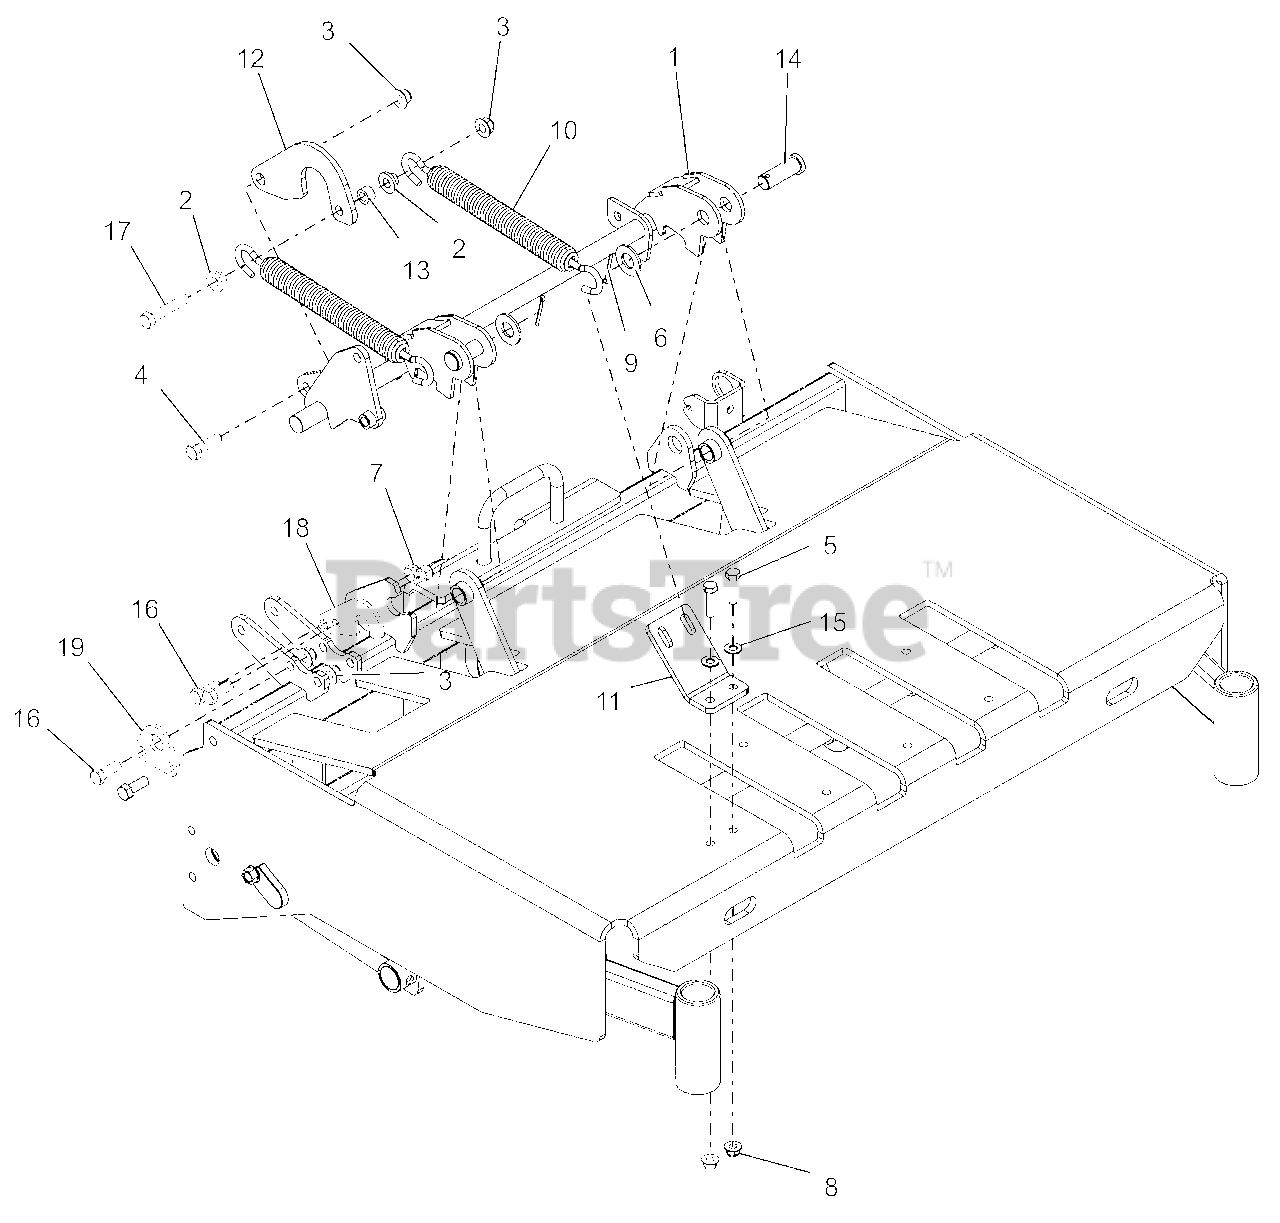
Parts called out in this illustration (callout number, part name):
1	WLDMT, CONTROL
2	BSHG-FLG .385X.500X.875X.406
3	NUT,NYL-FLG .38-16 GF ZCC
4	BLT, HEX .38-16X1.25 G5 ZCC
5	BLT, HEX .31-18X1.25 G5 ZCC
6	WSHRFLT 5/8SAE CARBHARD FBP
7	NUT,NYL .38-16 G5 ZCC
8	NUT,NYL-FLG .31-18 GF ZCC
9	PIN,CTR.12X1.25EXTPRSQCT ZC120
10	SPRING, EXTENSION
11	BRKT, SPRING LIFT
12	EAR, SPRG LIFT (RED)
13	BSHG-SLV .377X.624X.370
14	PIN, CLEVIS .625 X 1.75
15	WSHR,FLT .344X.688X.065 ZCC
16	BLT, HEX .38-16X1.00 G5 CKF
17	BLT,HEX .38-16X2.00 G5 ZCC
19	EAR,PIVOT END(RED)
